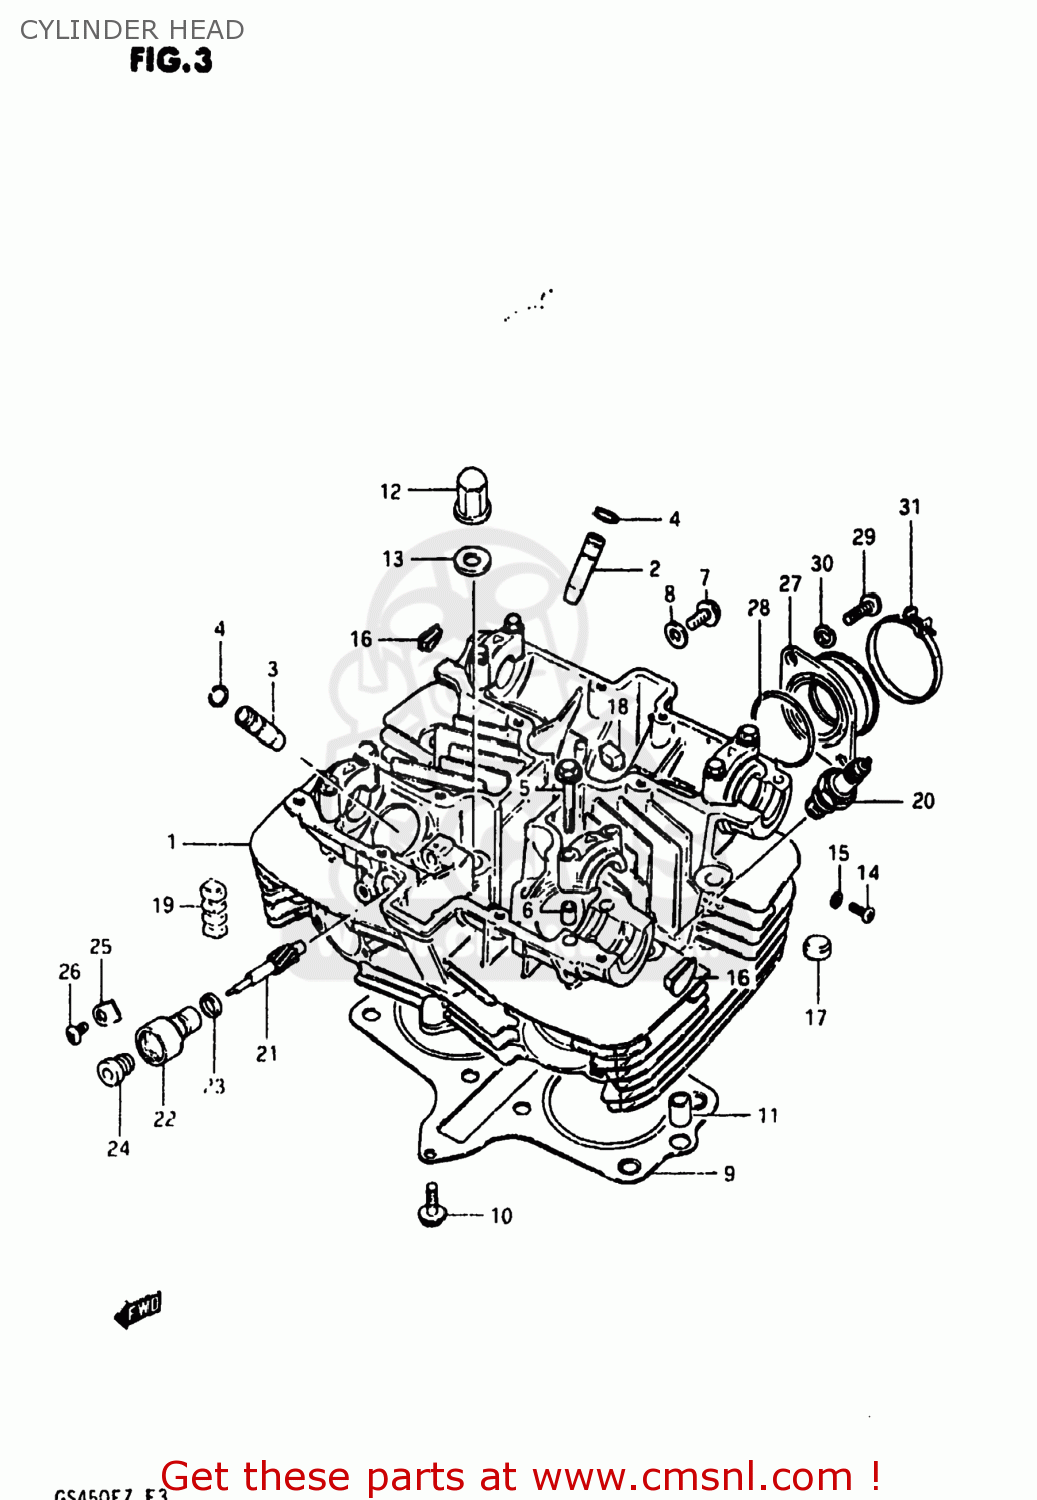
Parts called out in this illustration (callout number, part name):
1	HEAD ASSEMBLY,CYLINDER
2	GUIDE,INTAKE VALVE
3	GUIDE,EXHAUST VALVE
4	RING,SNAP
5	BOLT(6X39)
6	PIN(6.2X8X11)
7	BOLT
8	GASKET (NAS)
9	GASKET,CYLINDER HEAD (MCA)
10	BOLT
11	PIN
12	NUT
13	GASKET(10.5X22X2) (NAS)
14	SCREW
15	GASKET(5.3X9.3X1.2) (NAS)
16	PLUG
17	PAD,CYLINDER HEAD
18	PAD
19	PAD,CYLINDER
20	SPARK PLUG
21	GEAR,TACHOMETER DRIVEN
22	SLEEVE,TACHOMETER DRIVE
23	SEAL,TACHOMETER DRIVEN
24	SEAL,OIL(5X12X8)
25	PLATE,TACH DRIVE GEAR SLEEVE
26	SCREW(5X12)
27	PIPE,INTAKE
28	O-RING (D:2.4 ID:39.7)
29	SCREW
30	LOCK WASHER
31	CLAMP
